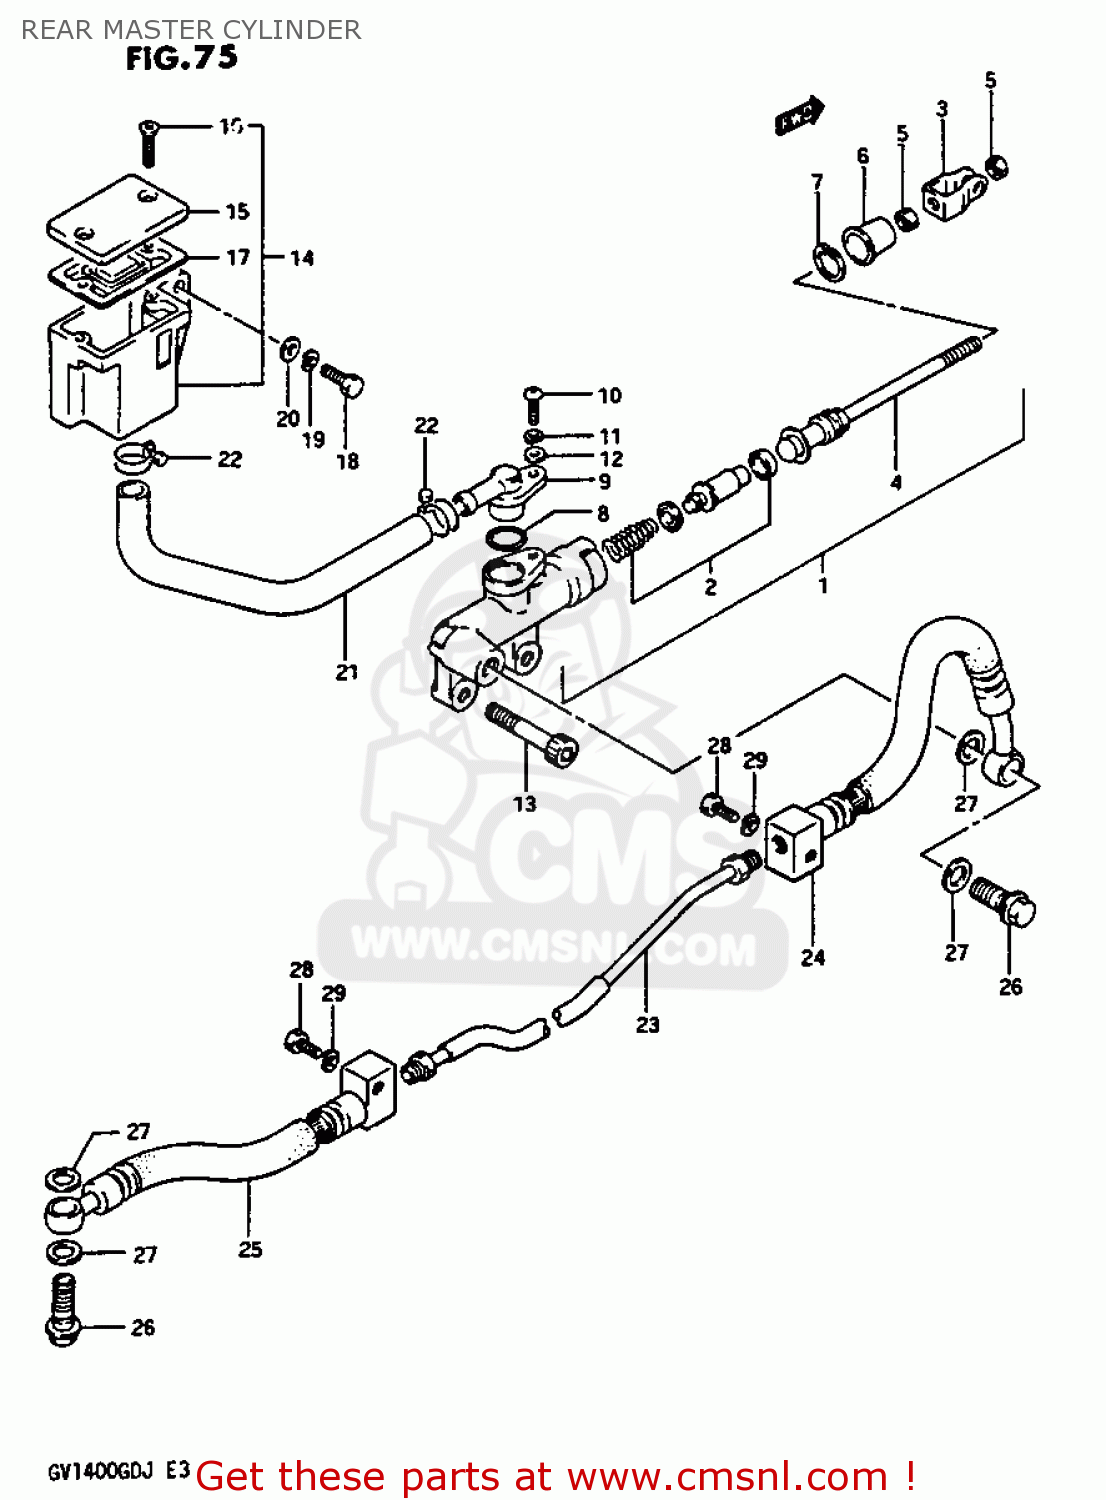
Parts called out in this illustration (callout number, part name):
1	CYLINDER ASSEMBLY,REAR MASTER
2	PISTON/CUP SET
3	YOKE
4	ROD,PUSH
5	NUT
6	BOOT
7	CIRCLIP
8	O RING
9	CONNECTOR
10	SCREW
11	LOCK WASHER
12	WASHER
13	BOLT 5X10
14	TANK ASSY,RESERVOIR
15	CAP
16	SCREW
17	DIAPHRAGM
18	BOLT
19	WASHER,LOCK
20	WASHER
21	HOSE,RESERVOIR TANK
22	CLAMP
23	PIPE,REAR BRAKE
24	HOSE,REAR BRAKE
25	HOSE,REAR BRAKE
26	BOLT UNION
27	WASHER(10X15X1.5)
28	BOLT
29	WASHER,LOCK
